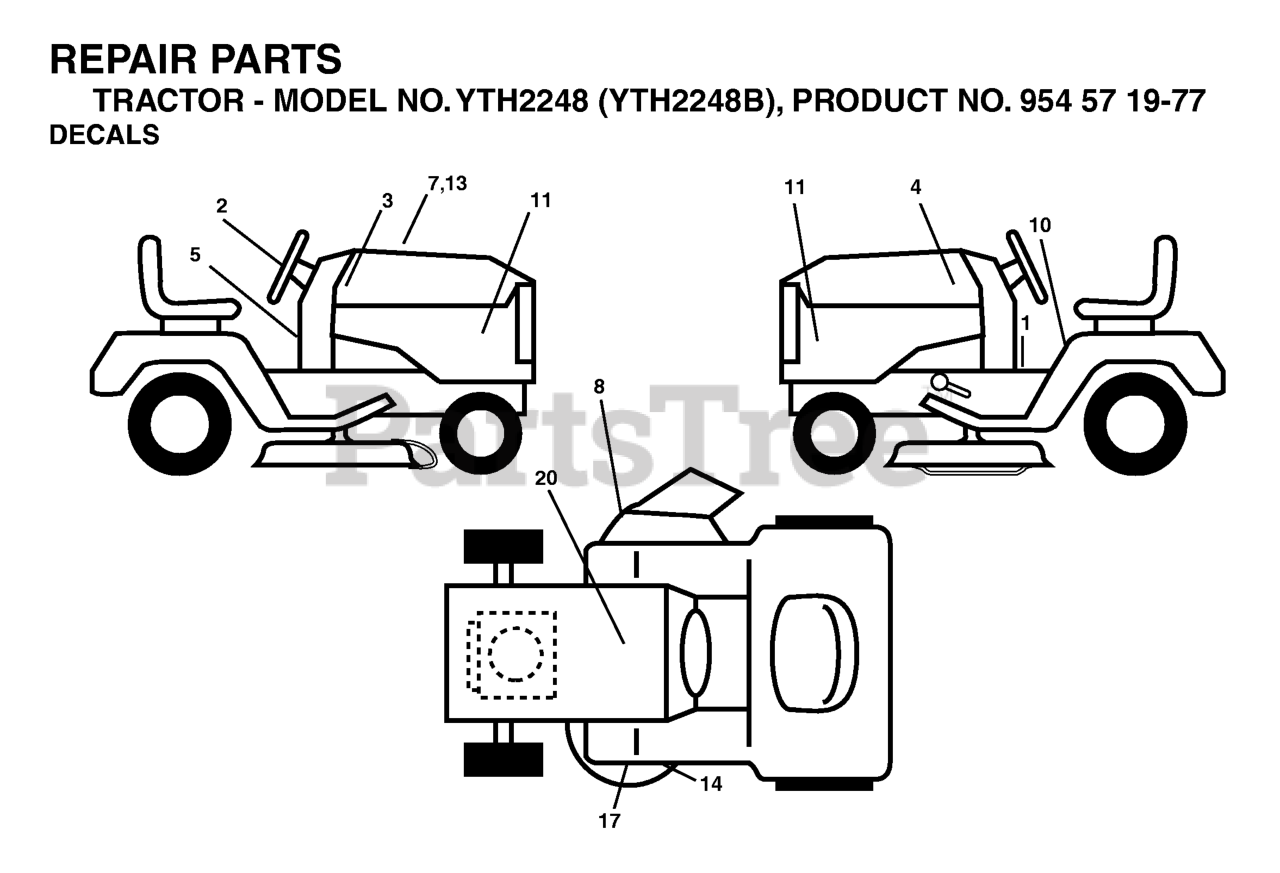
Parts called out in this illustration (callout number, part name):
2	DECAL.STEERING.HUSQ.BLUE
3	DECAL, HOOD RH
4	DECAL, HOOD LH
8	DECAL.WARN.KEEP.HAND.AWAY
10	DECAL FENDER DANGER
11	DECAL HOOD SIDES
13	DECAL HOOD CUST. RESP.
14	DECAL V-BELT SCHEMATIC
17	DECAL, MOWER HEAVY DUTY
20	DECAL BTRY SYMBOLS
